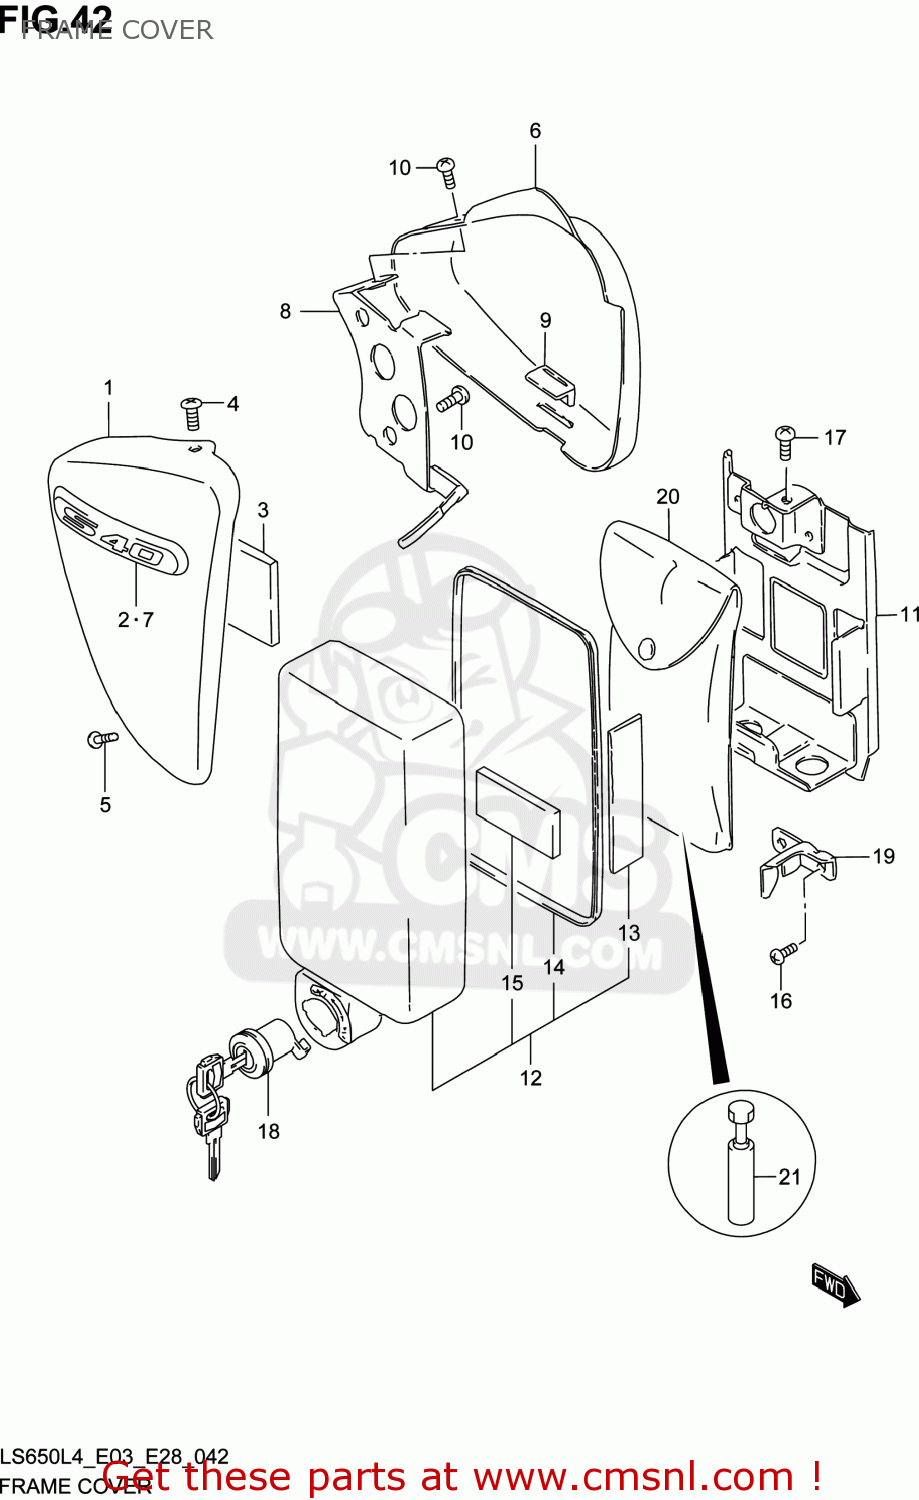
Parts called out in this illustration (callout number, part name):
1	COVER ASSY,FRAME,R(SILVER)
2	EMBLEM,FRAME COVER
3	PAD
4	SCREW
5	SCREW
6	COVER ASSY,FRAM
7	EMBLEM,FRAME COVER
8	BRACKET,FRAME COVER,L
9	CUSHION,FRAME COVER
10	SCREW
11	HOLDER,TOOL
12	COVER,TOOL HOLDER
13	PROTECTOR(20X90)X2
14	MOLDING
15	PROTECTOR(20X50X11)
16	SCREW
17	SCREW
18	LOCK SET,TOOL HOLDER
19	PLATE,TOOL HOLDER LOCK
20	TOOL ASSY
21	GAUGE ASSY,TENSION
